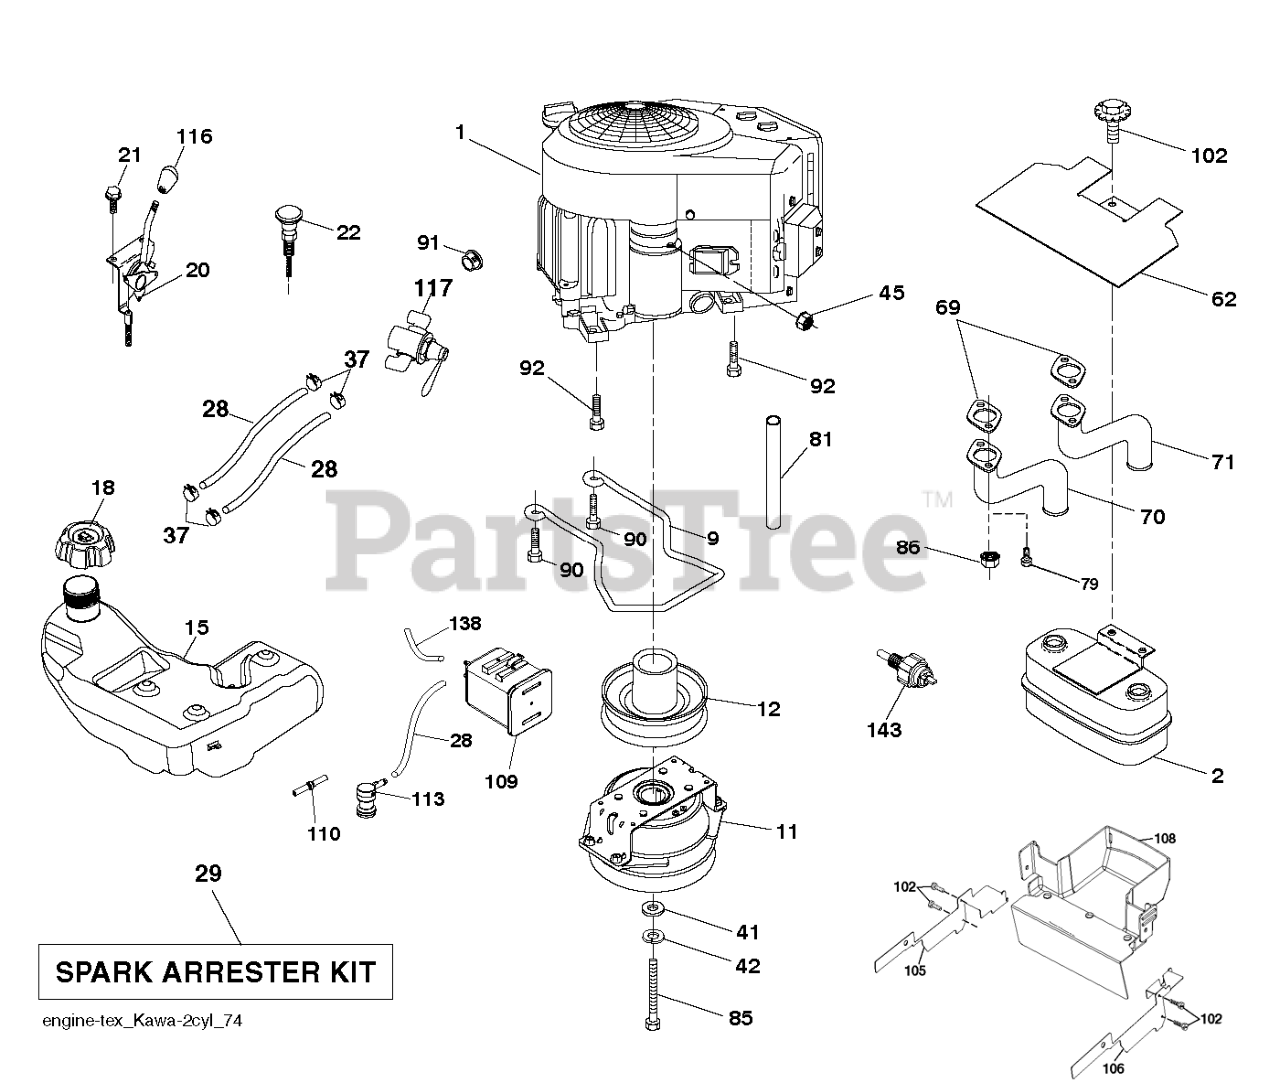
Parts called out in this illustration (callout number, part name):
2	MUFFLER.ASM.TWIN.MNTG.BRACKET
9	KEEPER.BELT.ENG.4.25"2.BLT.431
9	Keepers
11	CLUTCH.OGURA.5.0PD.GT1.5A-EH01
12	PULLEY ENGINE
12	PULLEY.EXTENDED.SHAFT.GROUND
15	TANK SUBASM; 4 GAL MFG YEAR 20
15	TANK.FUEL.4GAL
15	Tanks
15	TANK ASSY 4 GAL FUEL TANK ASM
15	TANK FUEL
18	FUEL CAP
18	CAP ASSY FUEL 3" GRAY
18	Fuel Caps
18	CAP.ASSY.FUEL.3".N-EPA.GRY.498
20	CONTROL.THROTTLE.PRO.
22	CONTROL, CHOKE
28	HOSE 1/4" LOW PERMEATION FUEL
28	LINE.FUEL.64"REAR.EMIS
28	HOSE.1/4".LOW.PERM.FUEL.LN.60"
29	KIT.SPARK ARRESTOR 794945 B&S
37	HOSE CLAMP
42	WASHER 7/16 LOCK
42	Washers
45	NUT
45	Hardware
62	SHIELD.HEAT.MUFFLER
69	GASKET
69	GASKET.MUFFLER
70	TUBE.EXHAUST.LH.FR961/FR730
70	EXHAUST.TUBE.LH.BS/TWIN
71	TUBE.EXHAUST.RH.FR961/FR730
71	EXHAUST.TUBE.RH.B&S.TWIN.INTEK
79	Screws
81	TUBE, DRAIN OIL ASM.
85	BOLT.HEX.7/16-20X3.GR5.YELLOW
86	NUT.HEX.FLANGE.TOPLOCK
90	SCREW 3/8-16X1
91	BUSHING.1.375OD
92	SCREW 3/8-16X1
102	SCREW
105	SHIELD 48 CLEARCUT EURO TRACTO
106	SHIELD 48 CLEARCUT EURO TRACTO
108	COVER 48 CLEARCUT EURO TRACTOR
109	CANNISTER, CARBON
110	VALVE.ASM.ANTI-SLOSH
113	VALVE.SLANT.CARTRDG.90 DEG.TEX
116	KNOB - SHIFT
117	VALVE FUEL RESERVE
138	PURGE.LINE.36"REAR.CALIFORNIA
143	SENSOR.SWITCH.PRESSURE.OIL
